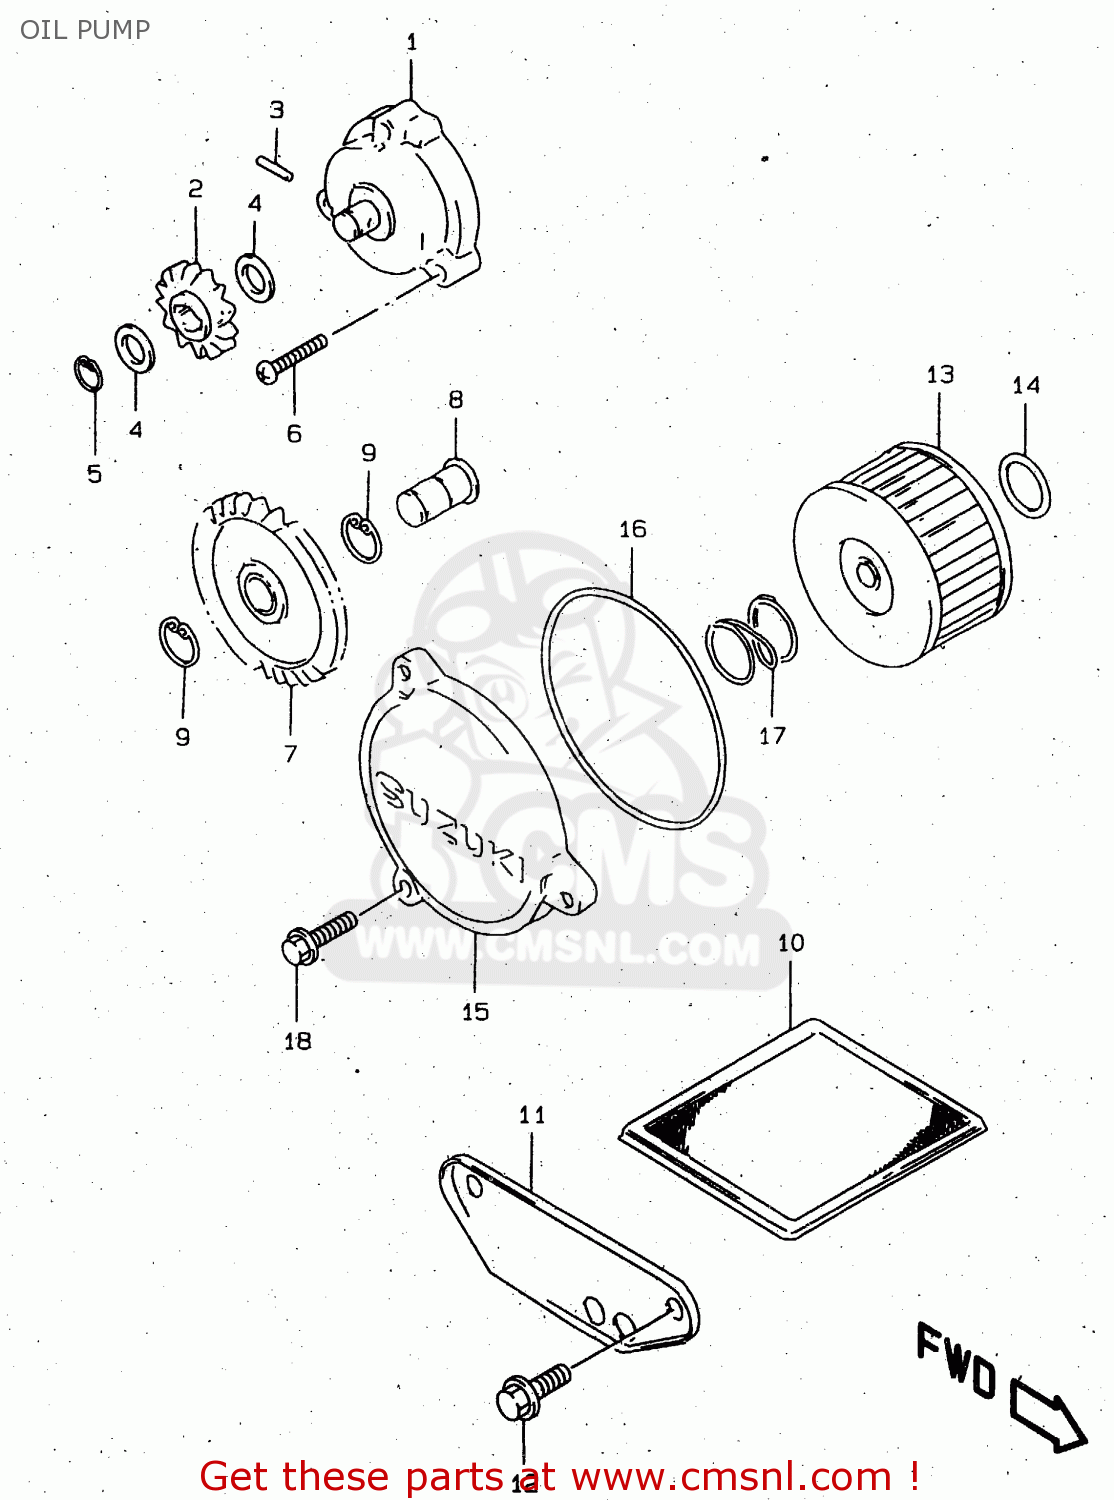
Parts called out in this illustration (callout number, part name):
1	PUMP ASSY,ENGINE OIL
2	GEAR,ENG OIL PUMP DRIVEN
3	PIN(4X15.8)
4	SHIM
5	CIRCLIP,10MM
6	SCREW
7	GEAR,OIL PUMP DRIVE(NT:30)
8	SHAFT,ENGINE OIL PUMP DRIVE
9	CIRCLIP,12 MM
10	STRAINER,ENGINE OIL
11	CAP,OIL STRAINER
12	BOLT 6X12
13	FILTER,ENGINE OIL
14	O RING(D:2.4,ID:15.8)
15	CAP,OIL FILTER
16	O RING(D:2.4,ID:73)
17	SPRING
18	BOLT
